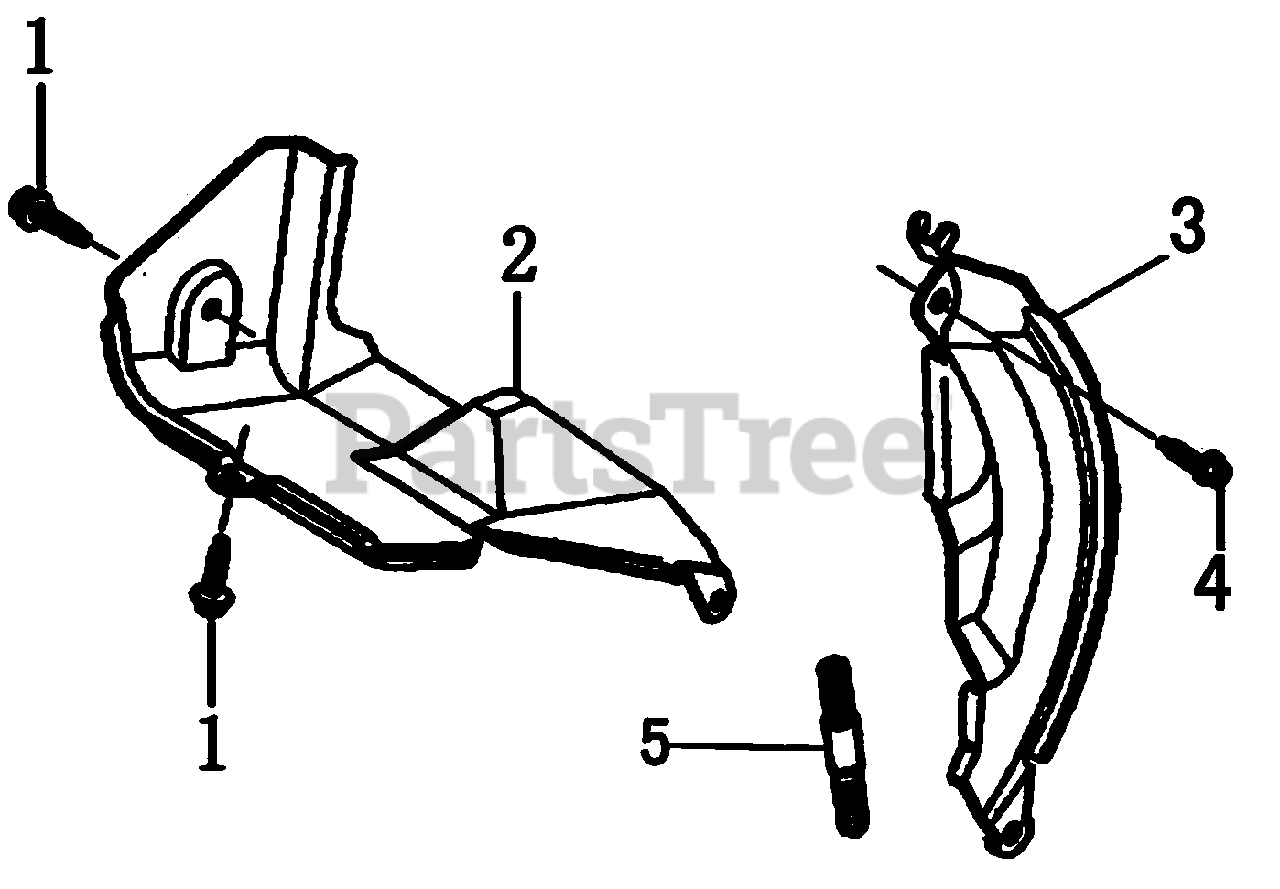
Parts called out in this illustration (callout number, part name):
1	BOLT, FLANGE 6X8
3	PLATE, SIDE
4	BOLT, FLANGE 6X20
5	BOLT, STUD
